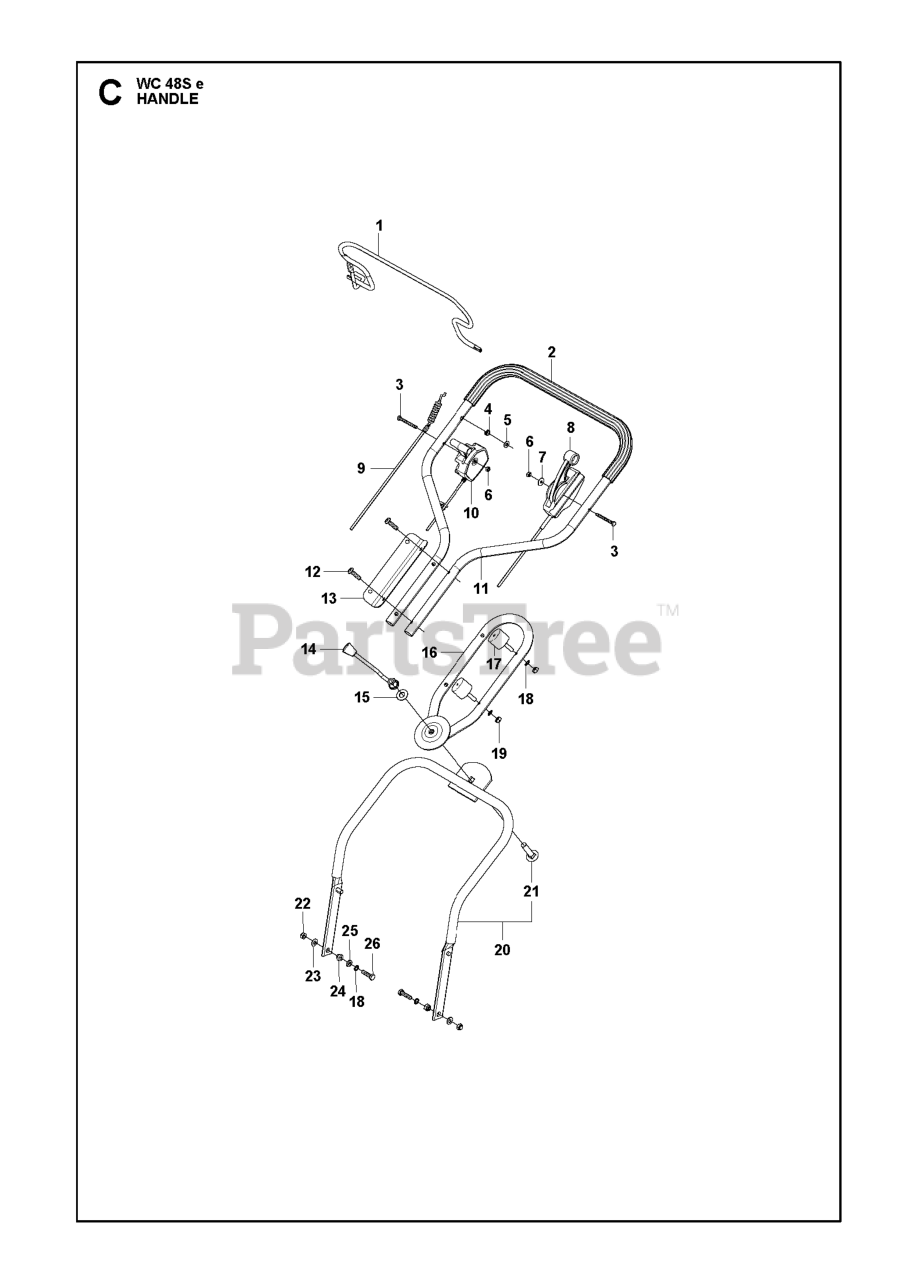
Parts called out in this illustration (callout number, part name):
3	SCREW M6X55
6	NUT FLANGE - M6
19	NUT
22	NUT LOCK - M8, NYLOCK
